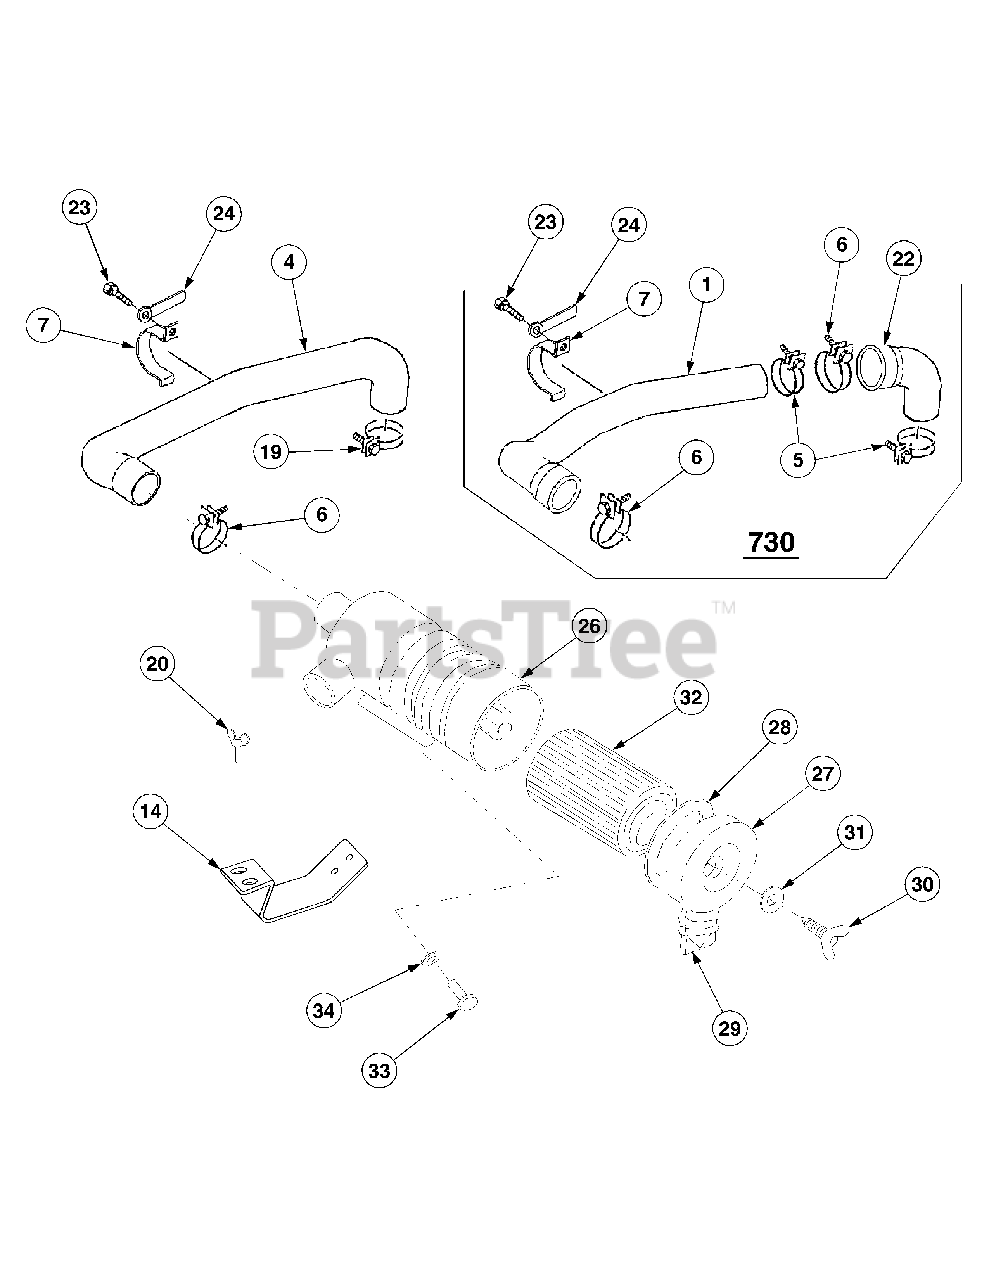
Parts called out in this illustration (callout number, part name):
26	Case Ass’y. (order assembly)
29	Valve, Unloader
32	Element
